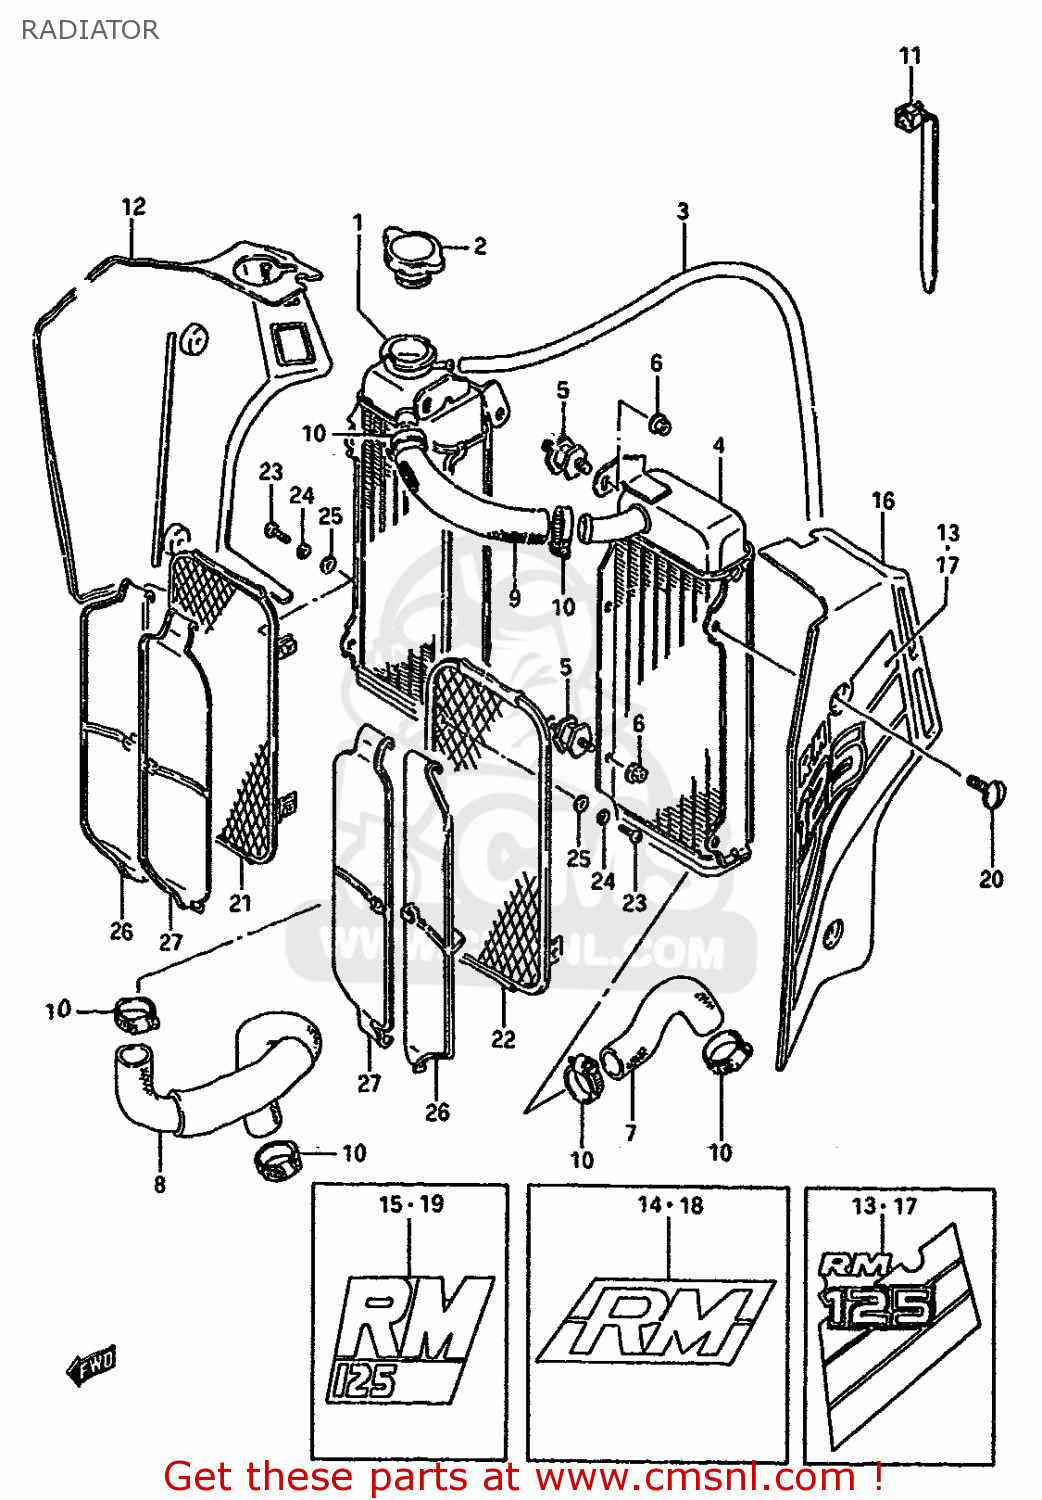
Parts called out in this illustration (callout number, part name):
1	RADIATOR COMP,WATER,RIGHT
2	CAP,RADIATOR 1.1
3	HOSE
4	RADIATOR COMP,WATER,LEFT
5	BOLT,RADIATOR CUSHION
6	NUT 6MM
7	HOSE,RADIATOR
8	HOSE,RADIATOR OUTLET
9	HOSE,RADIATOR JOINT
10	CLAMP
11	CLAMP(L:165)
12	COVER,RADIATOR
13	TAPE SET,RADIATOR COVER
14	TAPE SET,RADIATOR COVER STRIPE
15	EMBLEM,RADIATOR COVER
16	COVER,RADIATOR
17	TAPE SET,RADIATOR COVER
18	TAPE SET,RADIATOR COVER STRIPE
19	EMBLEM,RADIATOR COVER
20	SCREW(6X14)
21	BUMPER,RADIATOR,RIGHT
22	BUMPER,RADIATOR,LEFT
23	SCREW
24	WASHER,LOCK
25	WASHER
26	LOUVER,RADIATOR NO.1
27	LOUVER,RADIATOR NO.2
